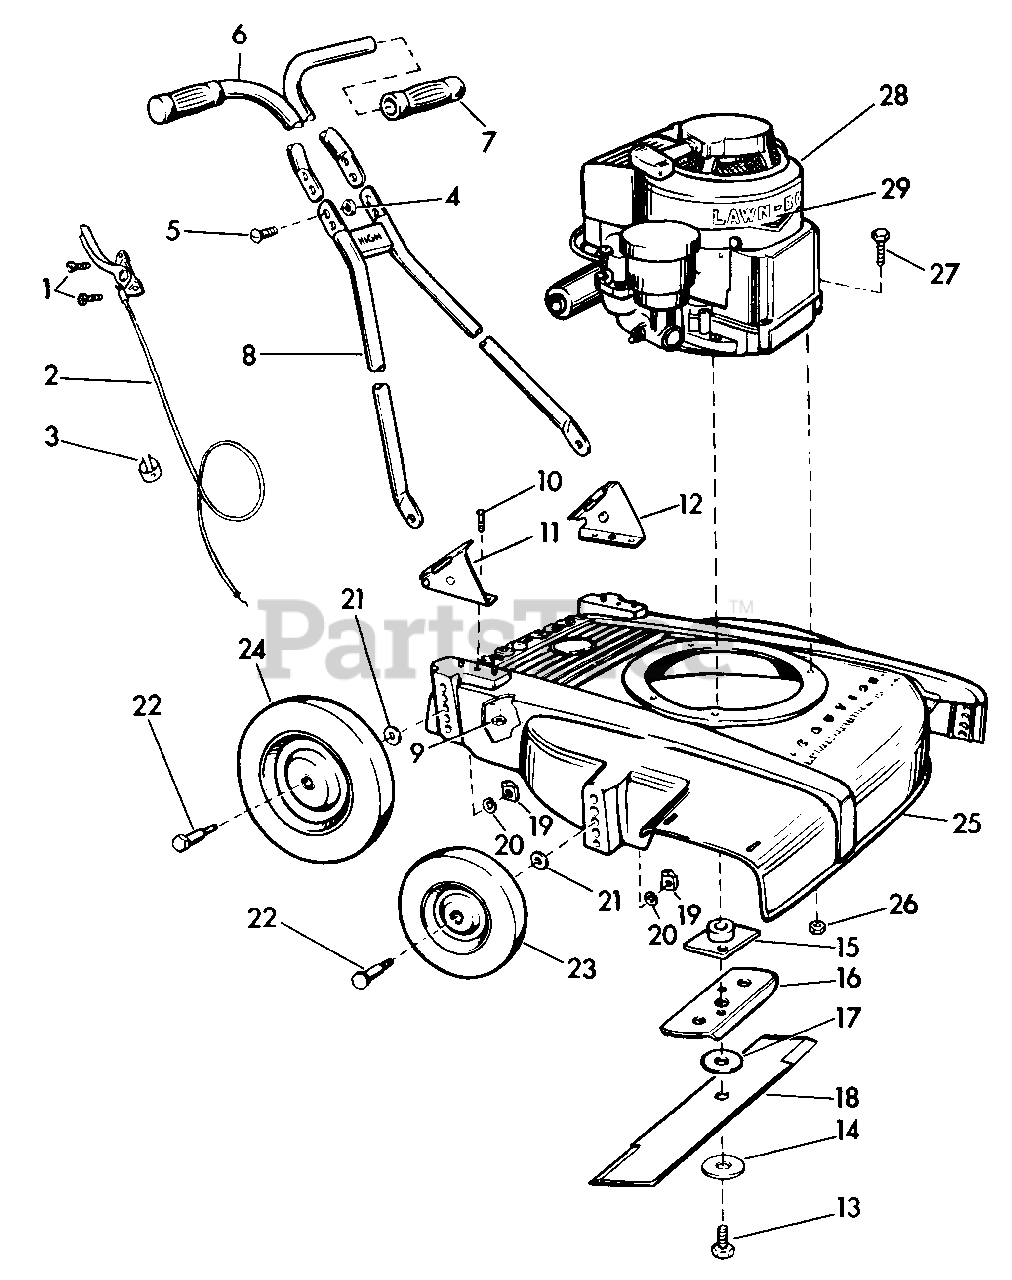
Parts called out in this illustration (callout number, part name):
1	Screw Control Mounting
2	Control Cable Assembly
3	Clip-Control Cable
4	Nut-Handle
5	Screw-Handle
6	Handle Assembly-Top
7	Grip-Handle
8	Handle Assembly-Bottom
9	Nut-Nylok Handle Bracket
10	Screw-Handle Bracket
11	Bracket-Handle, Right
12	Bracket-Handle, Left
13	Stud-Blade Mounting
14	Washer-Blade Mounting
15	Collar and Plate Assembly
16	Stiffener-Blade
17	Washer-Fiber (21" only)
18	Blade-18"
18	Blade-21"
19	Nut-Wheel
20	Washer-Lock, Wheel
21	Washer-Plain Wheel
22	Bolt-Shoulder Wheel
23	Wheel Assembly 6 x 1.50
24	Wheel Assembly 8 x 1.75
25	Housing-18"
25	Housing-21"
26	Nut-Engine Mounting
27	Screw-Engine Mounting
28	Engine-Model 8BHS, Briggs and Stratton
29	Decal-"Lawn-Boy"
